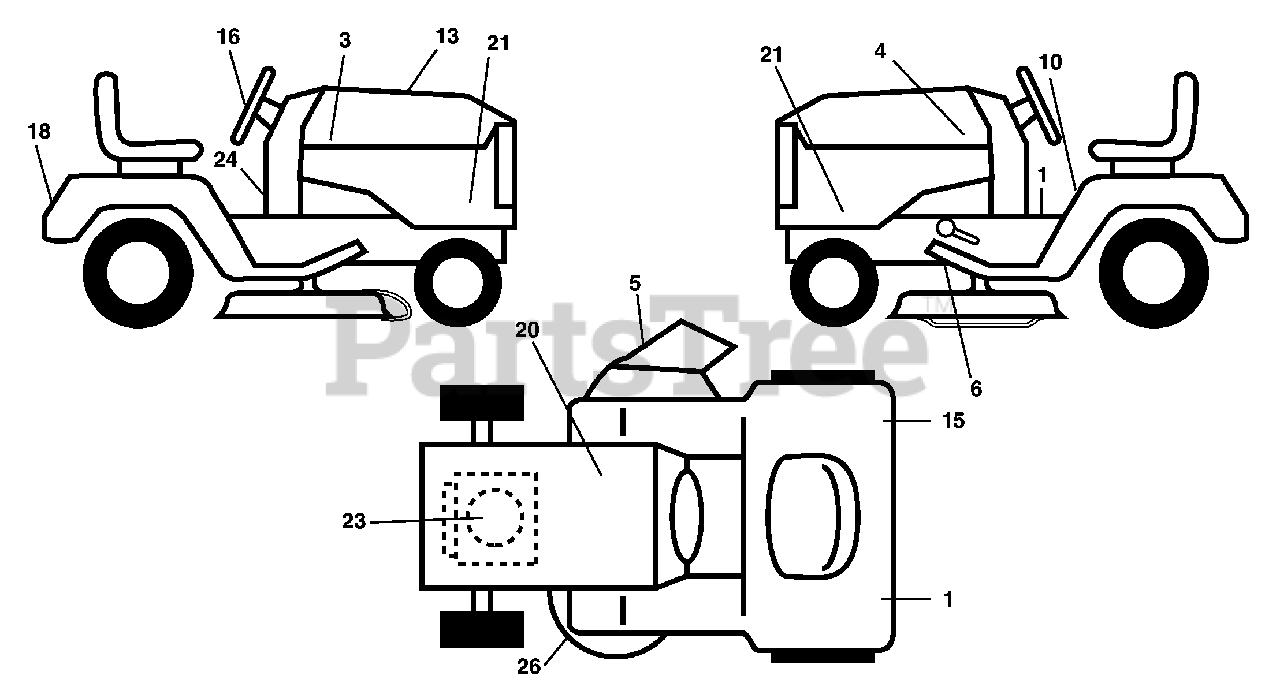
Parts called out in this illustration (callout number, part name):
1	Decal Reflector Lh
2	Decal Fender Oper
3	Decal Hood Rh
4	Decal Hood LH
5	Decal Warning Mower
6	Decal V-Belt Schematic
10	Decal Fender Danger E/F
15	Decal Reflector Rh
16	Decal Ins Strg Whl
18	Decal Fender Logo
20	Decal Bat Dan/Psn
21	Decal Hood Side Panel
23	Decal Engine
24	Decal Dash
26	Decal Deck Caution
